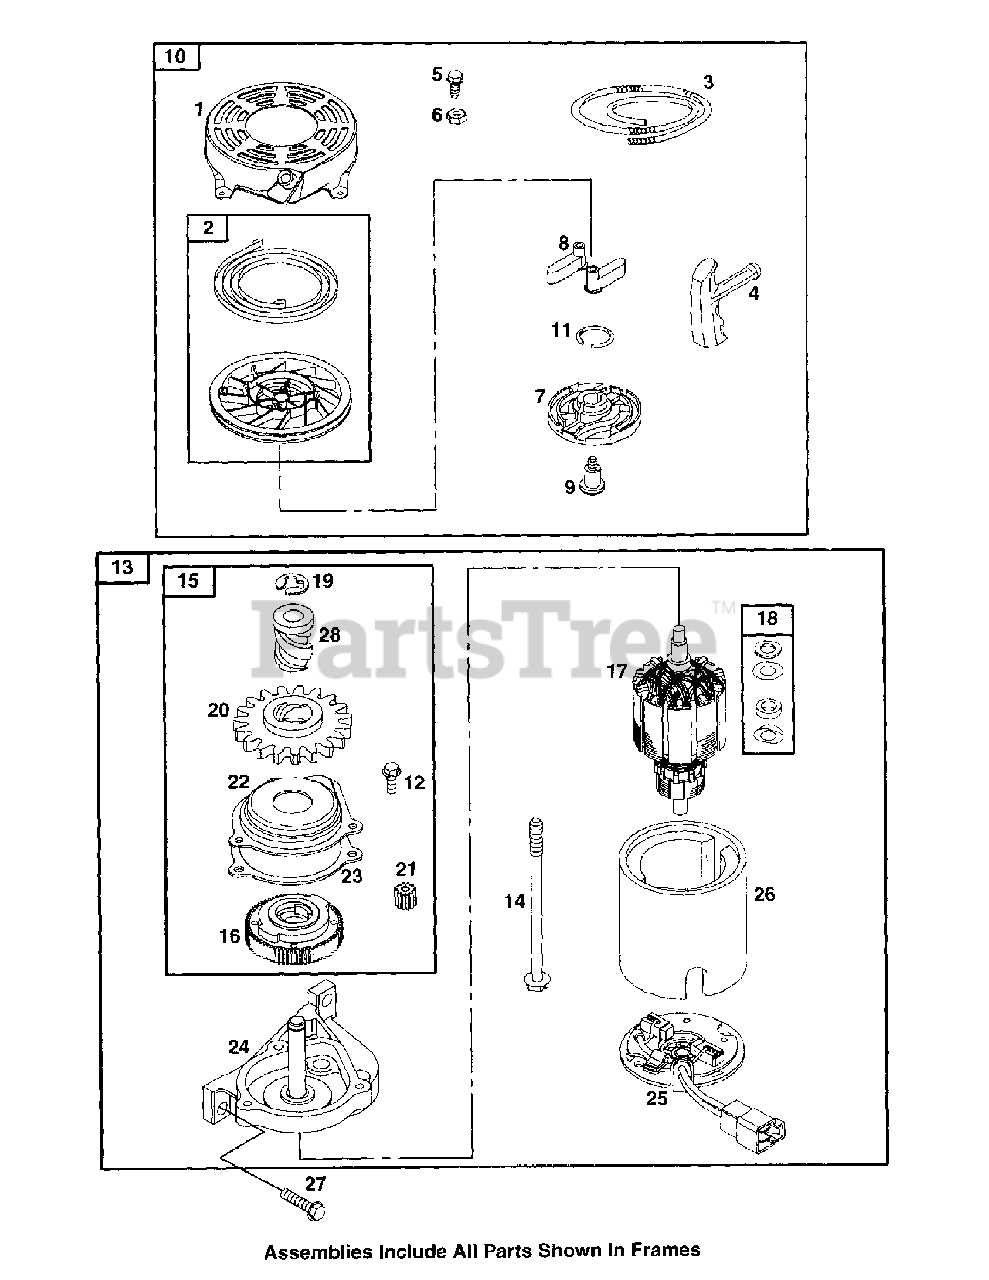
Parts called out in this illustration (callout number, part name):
1	Rewind Starter Housing
2	Starter Pulley
3	Starter Rope (Cut to 88-5/8")
4	Starter Rope Grip
5	Hex Screw
6	Hex Nut
7	Pawl Friction Plate
8	Ratchet Pawl
9	Shoulder Screw
10	Rewind Starter
11	Friction Spring
12	Hex Screw
13	Starter Motor (Model SC621E Only)
14	Slotted Hex Screw (Model SC621E Only)
15	Starter Drive (Model SC621E Only)
16	Drive Clutch (Model SC621E Only)
17	Starter Armature (Model SC621E Only)
18	Shim Set (Model SC621E Only)
19	Retainer (Model SC621E Only)
20	Pinion Gear (Model SC621E Only)
21	Pinion Gear (Model SC621E Only)
22	Gear Cover (Model SC621E Only)
23	Cover Gasket (Model SC621E Only)
24	Drive Cap (Model SC621E Only)
25	End Cap (Model SC621E Only)
26	Starter Housing (Model SC621E Only)
27	Hex Screw (Model SC621E Only)
28	Starter Spline (Model SC621E Only)
